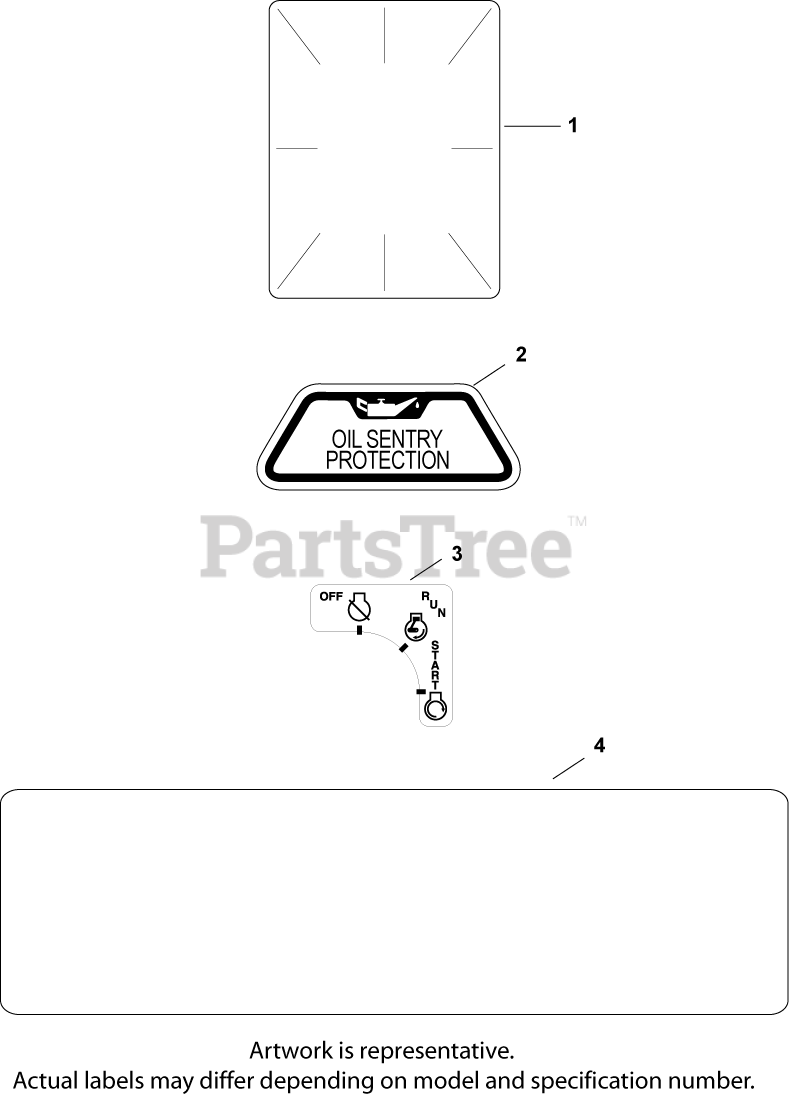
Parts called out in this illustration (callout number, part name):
1	DECAL, CLEAR LAMINATE USE 25 113 70-S
2	DECAL, OIL SENTRY - (#DSC)
3	DECAL, KEY SWITCH
4	DECAL, 18 HP
